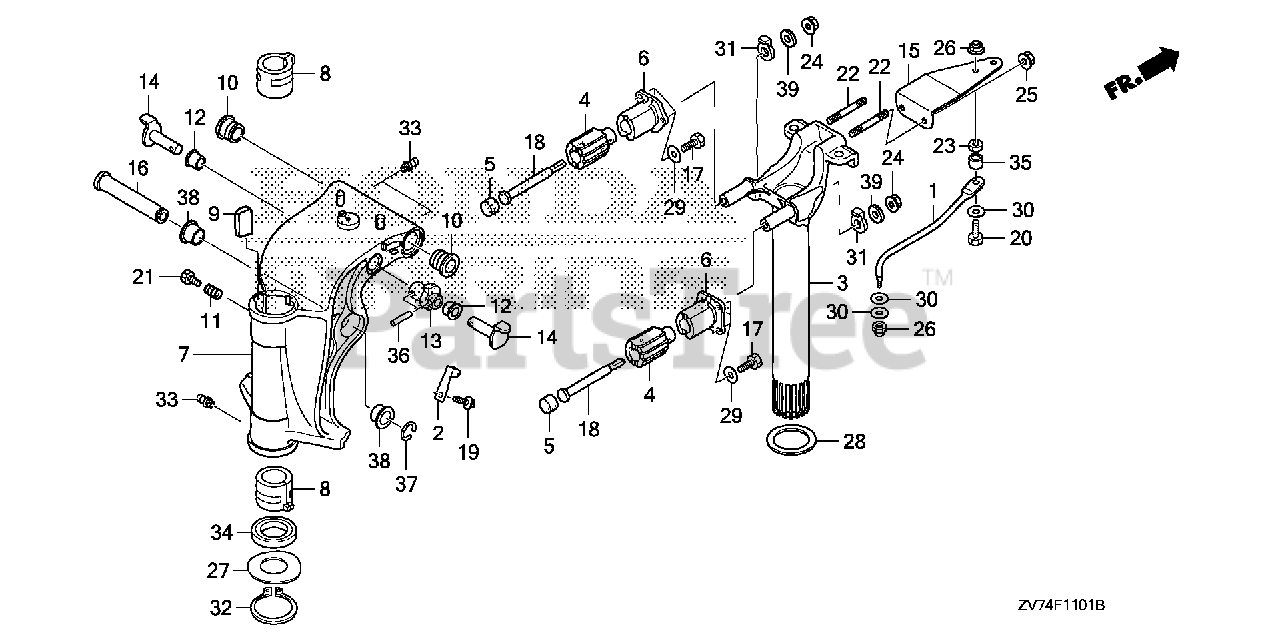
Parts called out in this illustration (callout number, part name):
1	ROD, STEERING
2	SPRING, CLICK
3	FRAME, MOUNTING
4	RUBBER, MOUNTING (UPPER)
5	RUBBER, MOUNTING (UPPER) (B)
6	HOLDER, MOUNTING (UPPER) *NH282MU* (OYSTER SILVER METALLIC-U)
6	HOLDER, MOUNTING (UPPER)
7	CASE, SWIVEL *NH282MU* (OYSTER SILVER METALLIC-U)
8	LINER, SWIVEL CASE
10	BUSH, SWIVEL CASE
12	BUSH, TILT ARM
13	BRACKET, TILTING
14	STOPPER, TILT
15	PLATE, STEERING
16	PIN, CYLINDER (UPPER)
17	BOLT, HEX. (6X18)
18	BOLT, SPECIAL (10X130)
19	BOLT, FLANGE (6X12)
20	BOLT (3/8-24UNF)
22	BOLT, STUD (10X28)
23	NUT (3/8-24UNF)
24	NUT, FLANGE (10MM)
25	NUT, SELF-LOCK (10MM)
26	NUT, SELF-LOCK (3/8-24UNF)
27	WASHER, WAVE (40MM)
28	WASHER, THRUST (34MM)
29	WASHER, PLAIN (6MM)
30	WASHER (10MM)
31	WASHER, SPECIAL
32	CIRCLIP (OUTER) (39MM)
33	NIPPLE, GREASE
34	OIL SEAL (39.5X52X6) (ARAI)
35	COLLAR, STEERING ROD
36	PIN, SPRING (2.5X20)
37	E-RING (15MM)
38	BUSH, CYLINDER (LOWER)
39	WASHER, PLAIN (10MM)
